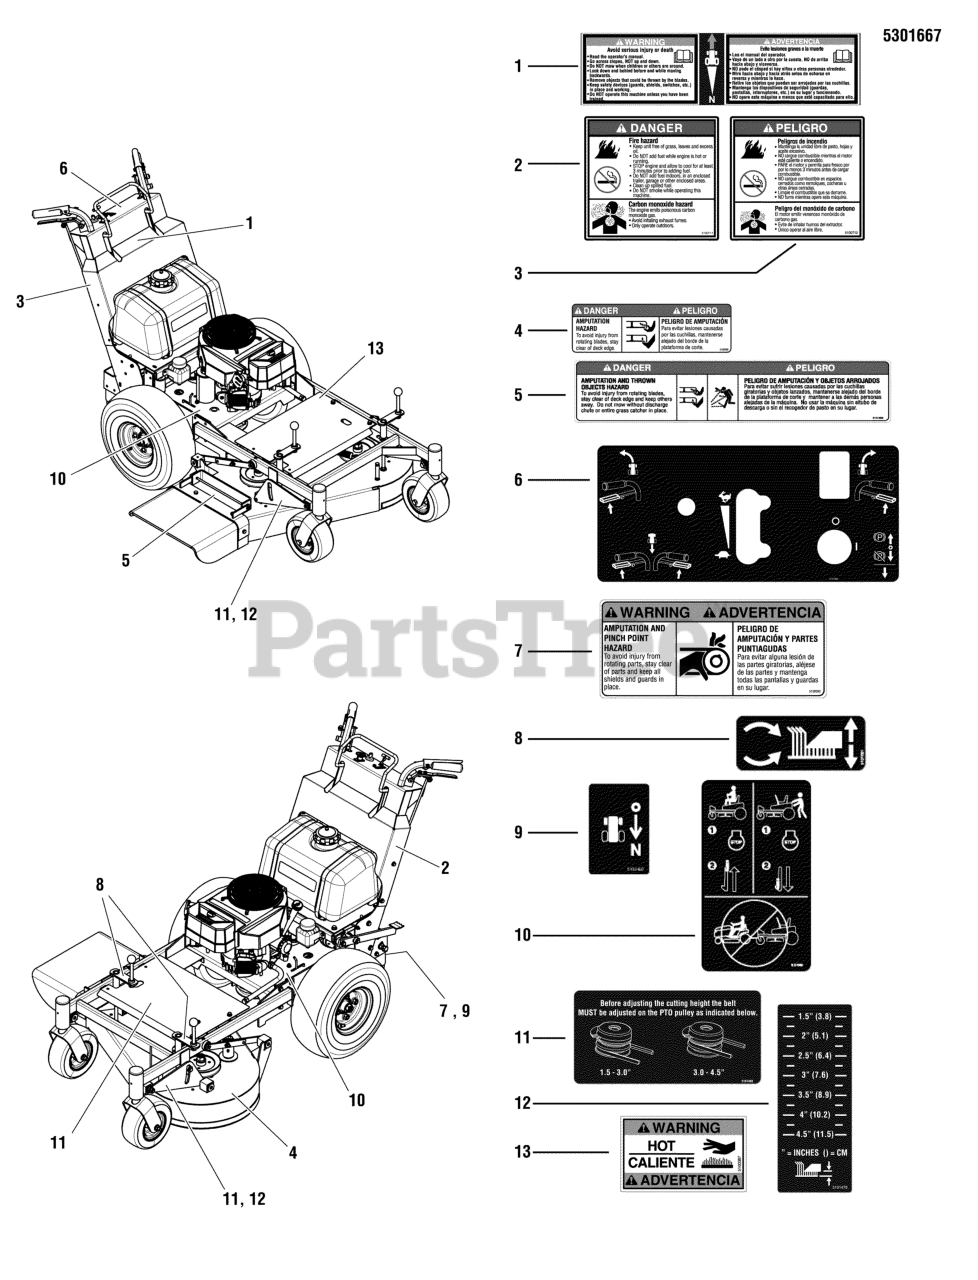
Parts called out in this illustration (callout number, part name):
1	DECAL, WARNING
2	DECAL, DANGER
3	DECAL, DANGER, FIRE (SP)
4	DECAL, DANGER, MOWER
5	DECAL, DANGER, MOWER DISCHARGE, SPDD
6	DECAL, CONTROL PANEL
7	DECAL, WARNING, HAND IN PULLEY
8	DECAL, CUT HEIGHT, SPDD
9	DECAL, PEDAL
10	DECAL, TRANSAXLE RELEASE
11	* DECAL, BELT LOCATION, PTO, SW20
12	DECAL, CUT HEIGHT, SW-20
13	DECAL, WARNING HOT
